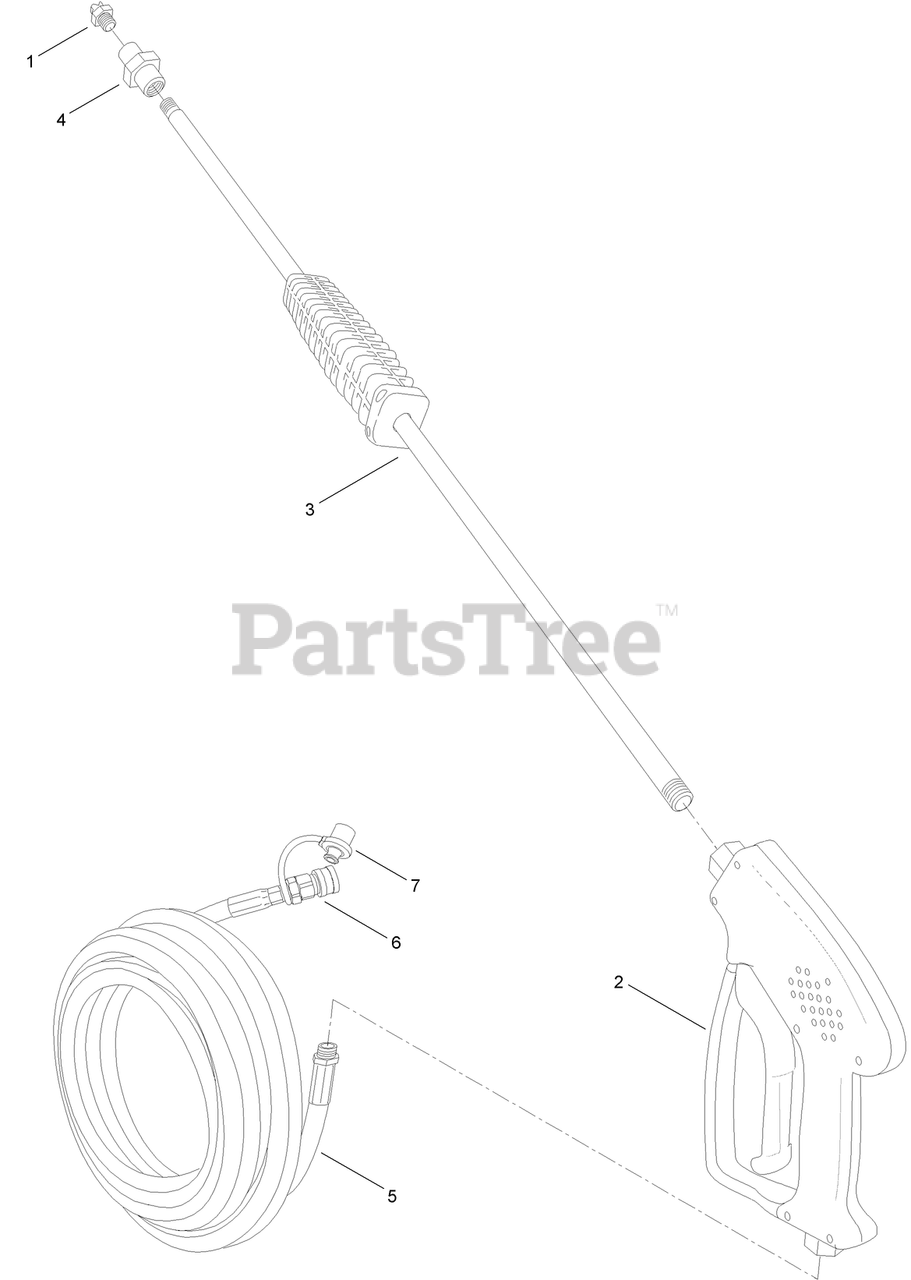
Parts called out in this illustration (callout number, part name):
1	NOZZLE-SPRAY
2	GUN-SPRAY
4	COUPLING-PIPE
5	HOSE-HYD
6	COUPLER-CONNECT, QUICK
7	PLUG-DUST
